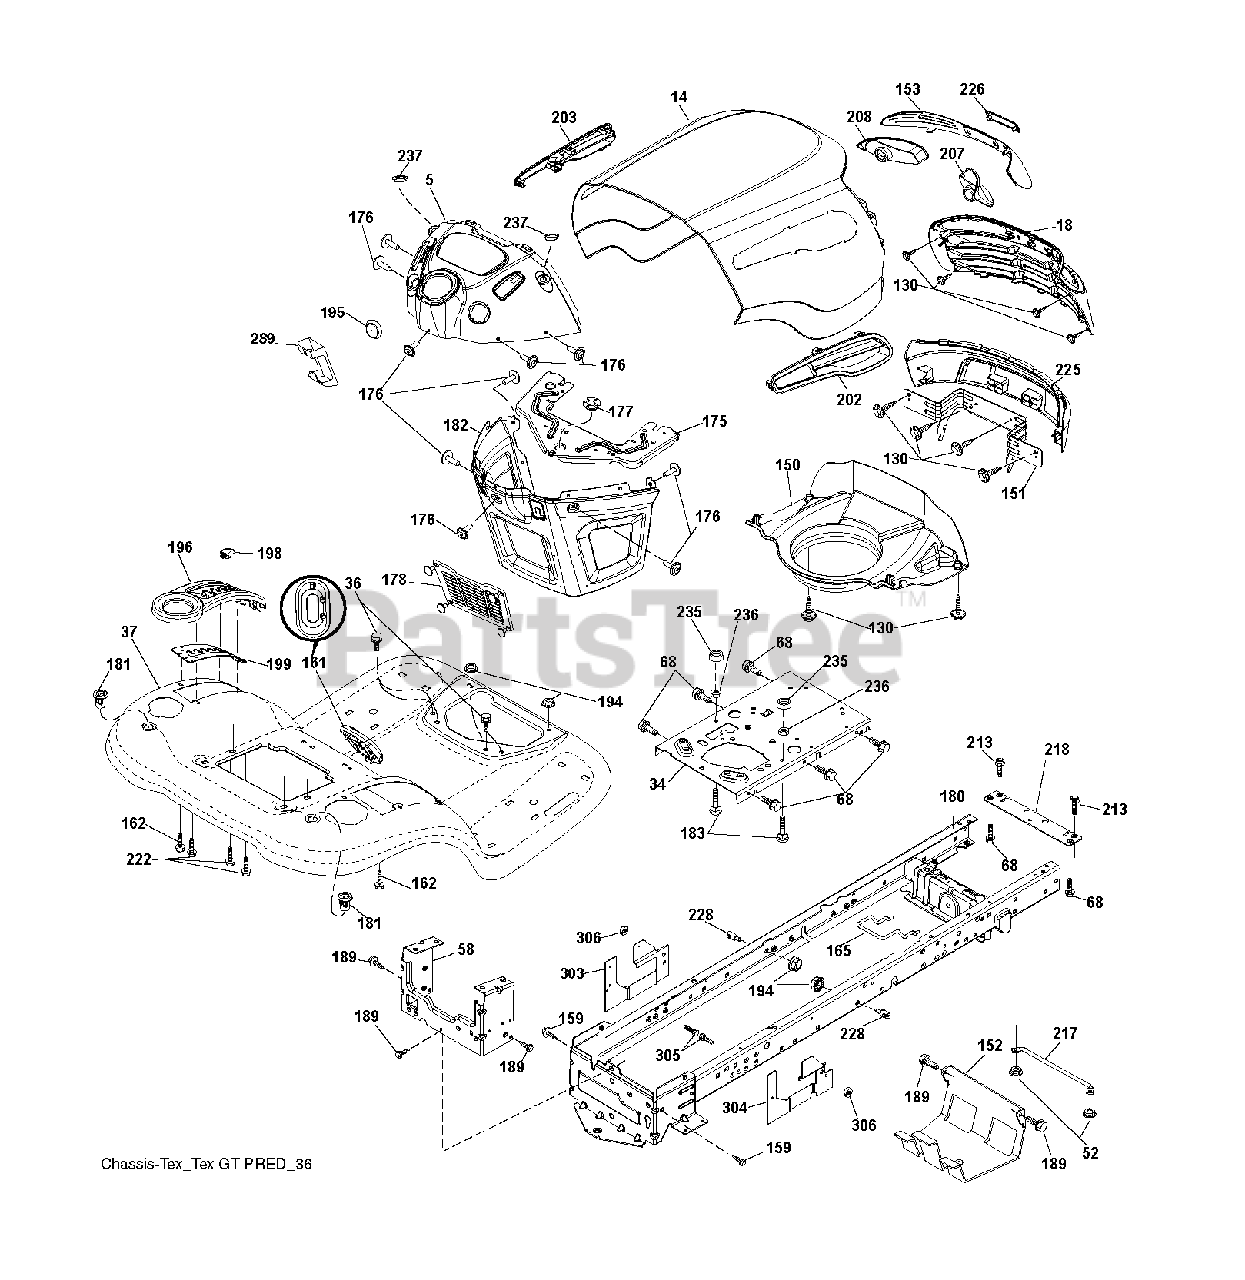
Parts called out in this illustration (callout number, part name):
34	PLATE.ENGINE.WELDED.CHASSIS
36	SCREW 5/16"
52	LOCKNUT
58	DRAWBAR.UPPER.2PC,LRG.FENDER
130	SCREW.#10 X 0.750.BOS THREAD
152	SHIELD BROWNING
159	SCREW, 3/8-16X3/4
161	CONSOLE.FUEL.WINDOW.STGT.BLACK
162	SCREW.HI-LO.CONSOLE
165	SUPPORT.TANK.REAR.W/TE
175	PLATE.CROSSMEMBER.HUSQ
176	SCREW.#10-24X5/8.RN.QU
177	BUSHING,STEERING
178	CARGO.ASM.NET.TXGT.W/C
180	CHASS.WLDMNT.TLT.12GA/2PC.20"
181	FEND/FTRST.PCH.CPH.NFW
182	DASH.LOWER.COMMON.12V.ADAPTOR
183	BOLT.5/16-18X1-1/4 FULL.THREAD
189	SCREW
194	NUT LOCK HEX FLANGE 5/16-18
195	PLUG.HOLE.DASH.LOWER.12V.BLK
198	INDICATOR DECK LIFT
199	PLATE DECK LIFT
213	BOLT
217	ROD.PIVOT.HOOD
218	X-PIECE.HOOD.STOP.NON/
222	SCREW.1/4-20X5/8
228	STUD.FASTNER.W/ANTI-ROTATE
235	SPACER FENDER
236	NUT.CENTERLOCK.5/16-
237	PLUG.MOUNT.CARGO.BLK
289	PLUG.N/CRUISE.COMMON.YT/GT.BLK
306	NUT LOCK FLG 3/8-16 UNC
